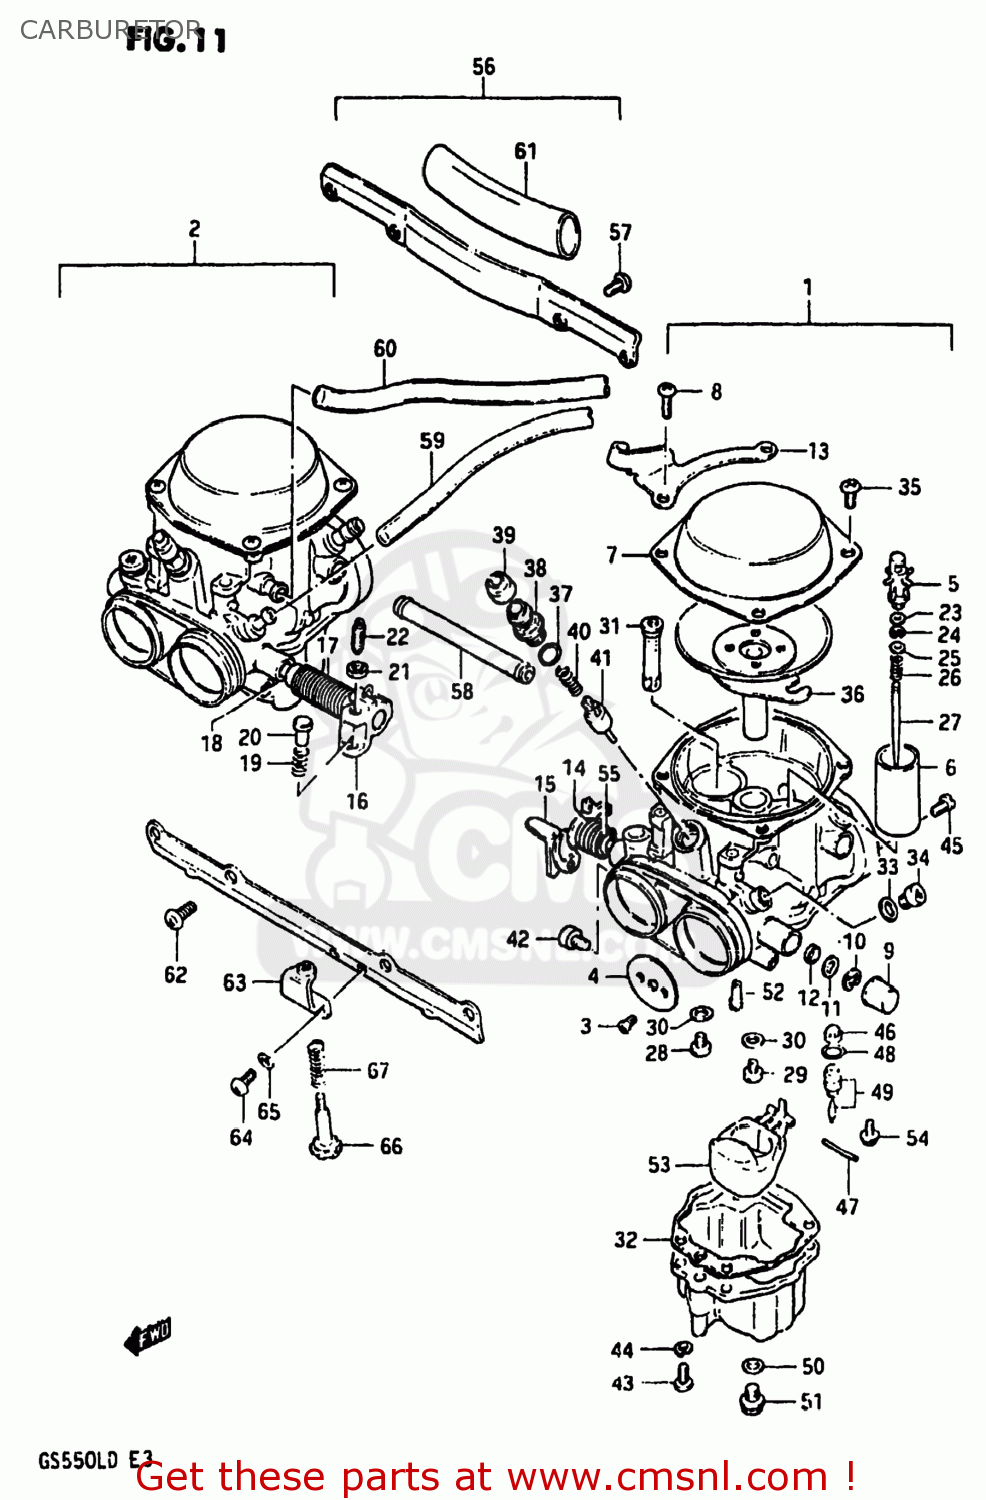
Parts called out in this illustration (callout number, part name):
1	CARBURETOR,LEFT
2	CARBURETOR,RIGHT
3	SCREW
4	VALVE,THROTTLE
5	HOLDER,GUIDE
6	VALVE,THROTTLE
7	COVER,DIAPHRAGM
8	SCREW
9	CAP
10	E RING
11	GASKET,THROTTLE SHAFT (NAS)
12	SEAL
13	BRACKET
14	SPRING,THROTTLE SHAFT
15	SHAFT ASSEMBLY
16	SHAFT ASSEMBLY
17	SPRING
18	RING
19	SPRING,THROTTLE SCREW
20	PIN,THROTTLE LEVER
21	NUT
22	SCREW
23	RING
24	CAP,LEVER
25	WASHER
26	SPRING
27	NEEDLE JET
28	JET,MAIN(95)
29	JET,MAIN(105)
30	WASHER,NEEDLE NOZZLE
31	JET,NEEDLE
32	GASKET,FLOAT CHAMBER (MCA)
33	WASHER
34	SCREW
35	SCREW
36	DIAPHRAGM,CARBURETOR
37	O RING
38	HOLDER,GUIDE
39	CAP
40	SPRING
41	VALVE,STARTER
42	SCREW
43	SCREW
44	LOCK WASHER
45	JET,PILOT(150)
46	FILTER
47	PIN,FLOAT
48	O-RING,NEEDLE VALVE
49	VALVE ASSEMBLY,NEEDLE
50	GASKET (NAS)
51	PLUG,DRAIN
52	JET,PILOT(35)
53	FLOAT
54	SCREW
55	RING,THROTTLE SHAFT
56	FLANGE ASSEMBLY,CARBURETOR
57	SCREW
58	PIPE,CARBURETOR
59	HOSE
60	HOSE
61	HOSE
62	SCREW 6X12
63	BRACKET
64	SCREW
65	LOCK WASHER
66	ADJUSTER
67	SPRING
